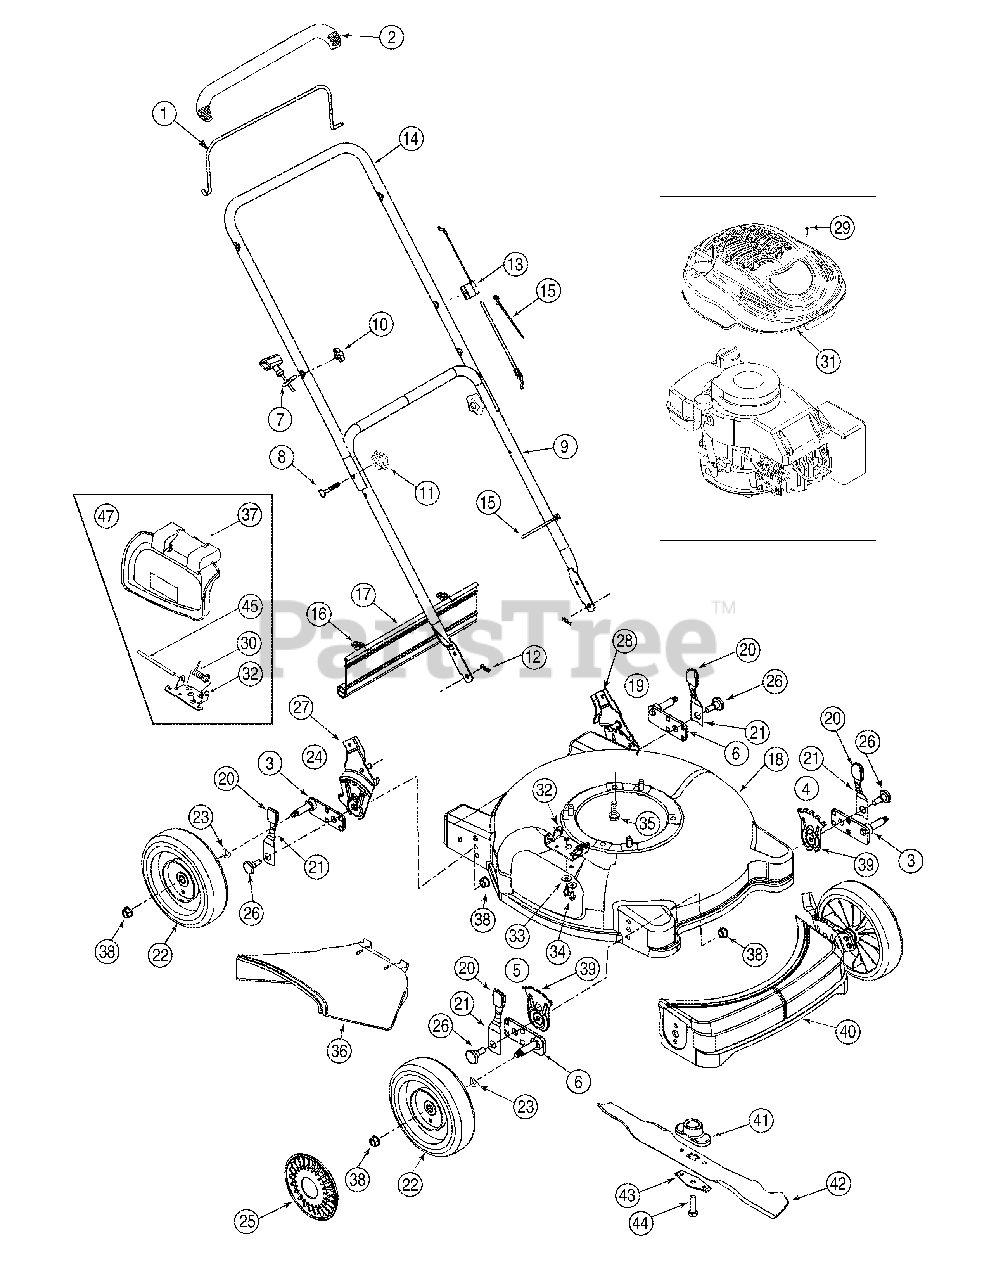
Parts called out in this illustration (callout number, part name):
2	Deluxe Cover - Black
2	Deluxe Cover - Red
2	Deluxe Cover - Grey
3	Pivot Arm LH
4	Hgt. Adjust Ass’y LH
5	Hgt. Adjust Ass’y RH
6	Pivot Arm RH
7	Rope Guide Bolt
8	Carriage Bolt 5/16-18 x 2.0
9	Lower Handle
10	Knob - ERS Guide 1/4-20
11	Knob - Star 5/16-18
12	Int. Cotter Pin .072 x 1.13" Lg.
13	Control Cable 37.25 " Lg. (Honda)
15	Cable Tie
17	Hinge Clip
20	Knob
21	Spring Lever
22	Wheel Ass'y 8" x 2.125" Idle BB
22	Wheel Ass'y 8" x 2.0" S-Wave BB
23	Wave Washer .51" ID (w/bb wheels)
24	Rear Hgt. Adjust Ass’y RH
25	Hub Cap - Yellow Radial (optional)
25	Hub Cap - Grey Radial (optional)
26	Shoulder Screw .50 Dia. x .385
30	Torsion Spring
31	Shroud - Yellow
33	Cupped Washer .265 ID x .75 OD
34	Hex Wash S-Tapp Scr 1/4-20 x .50
35	Hex Wash HD Tap Scr 3/8-16 x .88
36	Chute Deflector
37	Mulching Plug
38	Flanged Lock Nut 3/8-16 Gr. F
39	Height Adjuster Plate
40	Front End Cover -Yellow (optional)
40	Front End Cover-Black (optional)
41	Blade Adapter
42	20" Mulching Blade
43	Blade Bell Support
44	Hex Bolt 3/8-24 x 1.5" Lg. (Grade 8)
45	Hinge Pin
47	Hinged Mulching Plug Ass'y
